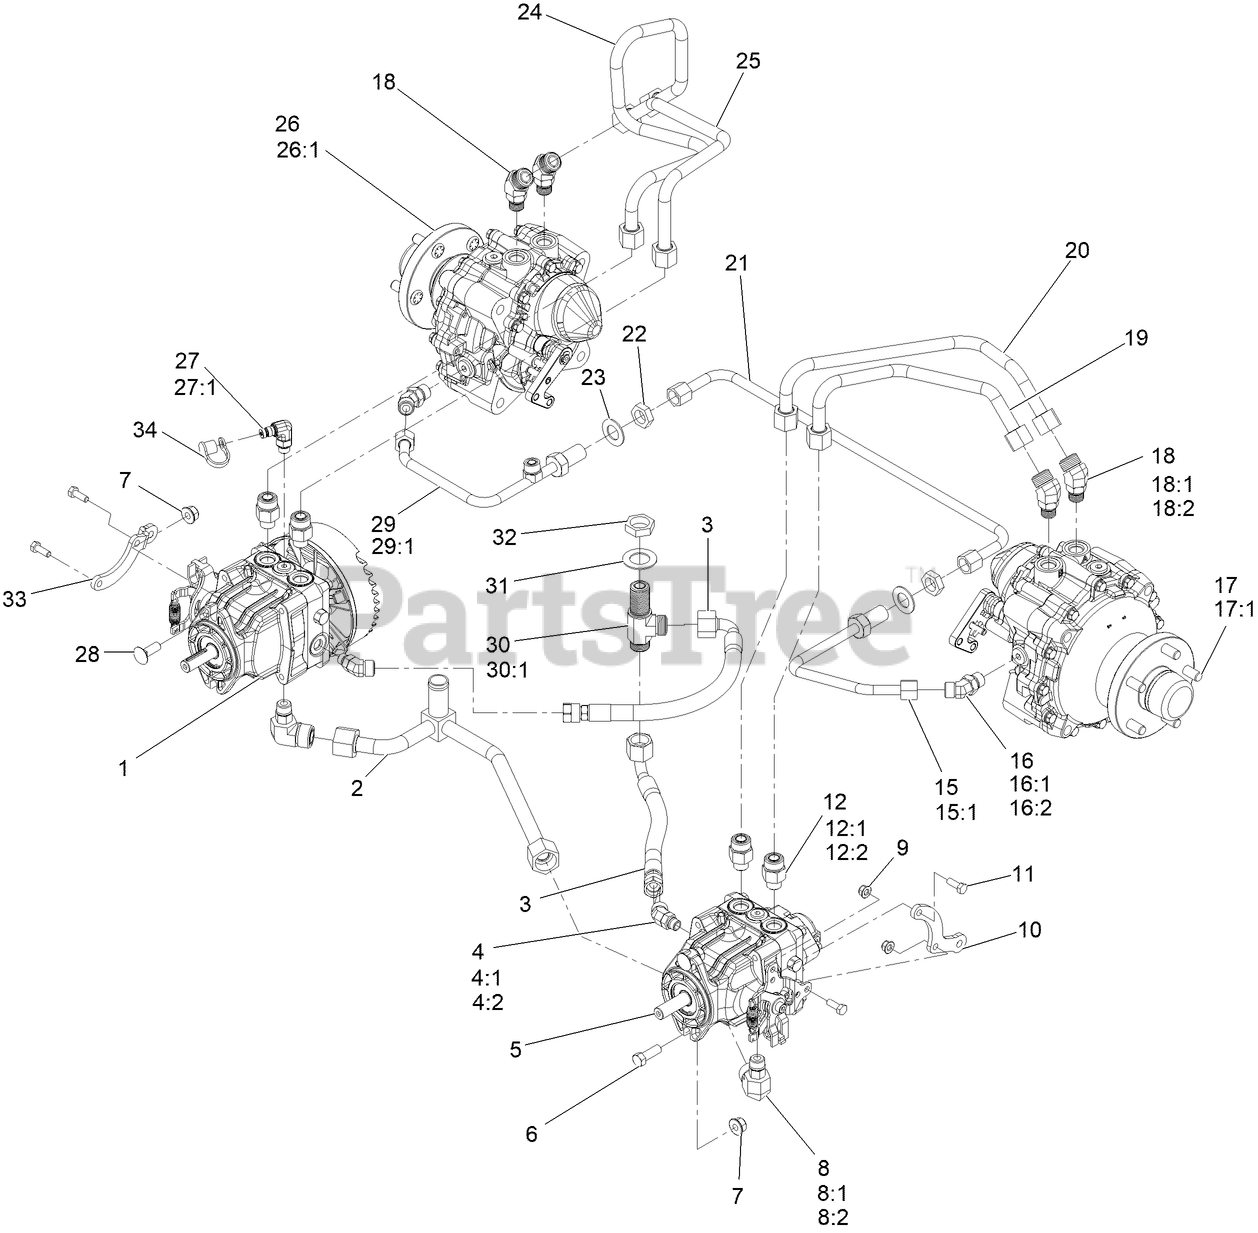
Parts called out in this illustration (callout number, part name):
1	PUMP-HYDRO RH 16CC W/ FAN
2	HYDRAULIC TUBE ASM
3	HYDRAULIC HOSE ASM
4	Adapter
4:1	O-RING
4:2	O-RING
5	Pump-Hydro, LH
6	SCREW-HH
7	NUT-HF, NI
8	FITTING-ELBOW, 90 DEG
8:1	O-Ring
8:2	O-RING
9	NUT-HF, NI
10	LEVER, PUMP
11	SCREW-HH
12	FITTING-STRAIGHT
12:1	O-RING
15	HYDRAULIC TUBE ASM
15:1	O-RING
16	FITTING-HYD, 45 DEG
16:1	O-RING
16:2	O-RING
17	MOTOR-HYD, LH
17:1	5 STUD WHEEL HUB KIT
18	FITTING-HYD, 45 DEG
18:1	O-RING
18:2	O-RING
19	HYDRAULIC TUBE ASM
20	HYDRAULIC TUBE ASM
21	HYDRAULIC TUBE ASM
22	NUT-BULKHEAD
24	HYDRAULIC TUBE ASM
25	HYDRAULIC TUBE ASM
26	MOTOR-HYD, RH
26:1	5 STUD WHEEL HUB KIT
27	FITTING-ELBOW-90
27:1	O-RING
28	BOLT-CARR
29	HYDRAULIC TUBE ASM
29:1	O-RING
30	FITTING-TEE
30:1	O-RING
32	NUT-LOCK, BULKHEAD
33	ARM-PUMP, RH
34	CAP-DUST
